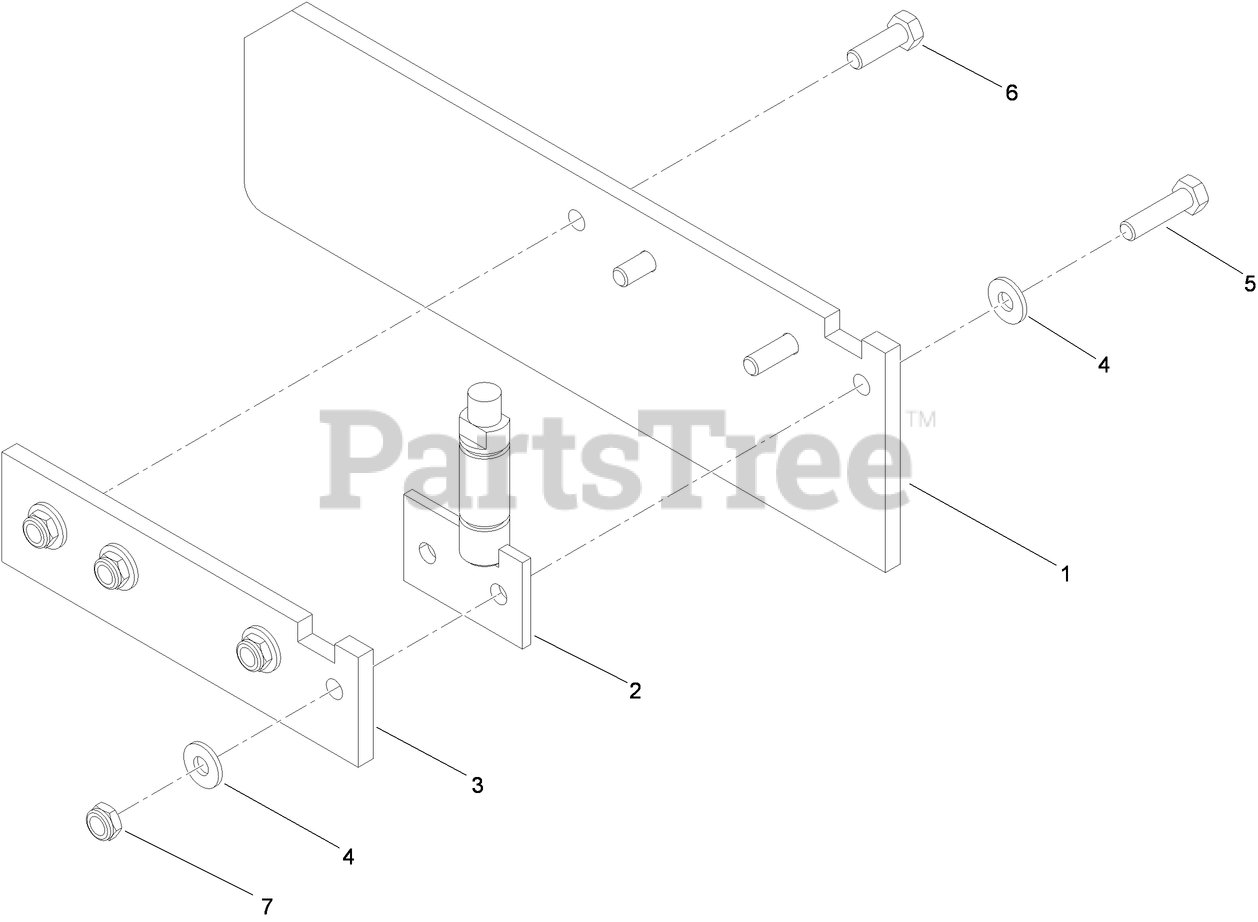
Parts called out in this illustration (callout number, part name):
1	GATE-CHUTE, RUBBER
2	HINGE-GATE
3	DOOR-SUPPORT
4	WASHER-FLAT
5	SCREW-HH
6	SCREW-HH
7	NUT-LOCK, NI
